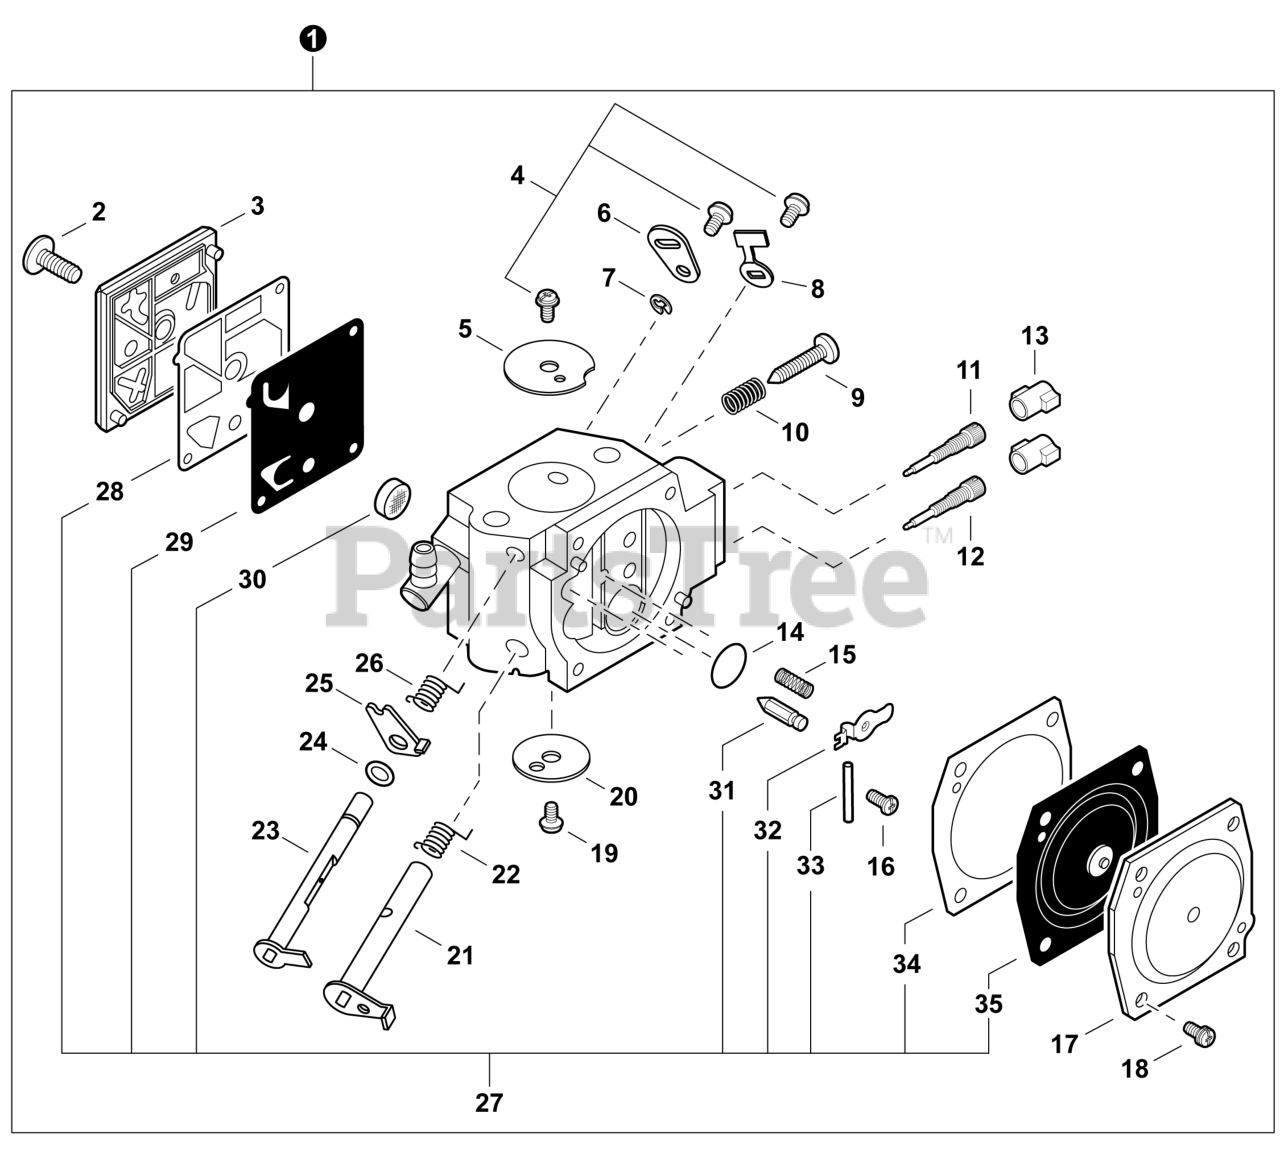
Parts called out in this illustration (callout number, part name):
1	CARBURETOR HDA-316
3	COVER, FUEL PUMP
5	VALVE, THROTTLE
6	LEVER, CHOKE
8	STOP, THROTTLE
9	SCREW, IDLE ADJUST
10	SPRING, IDLE ADJUST
11	NEEDLE, HIGH SPEED
12	NEEDLE LOW SPEED
13	CAP, LIMITER
14	PLUG, WELCH
16	SCREW, METERING LEVER PIN
17	COVER, METERING DIAPHRAGM
20	VALVE, THROTTLE
21	SHAFT, THROTTLE
22	SPRING, THROTTLE RETURN
23	SHAFT, CHOKE
25	LEVER, FAST IDLE
26	SPRING, CHOKE RETURN
27	REPAIR KIT
28	GASKET, FUEL PUMP
29	DIAPHRAGM, FUEL PUMP
30	SCREEN, FUEL INLET
31	VALVE, INLET NEEDLE
32	LEVER, METERING
33	PIN, METERING LEVER
34	GASKET, METERING DIAPHRAGM
35	DIAPHRAGM, METERING
